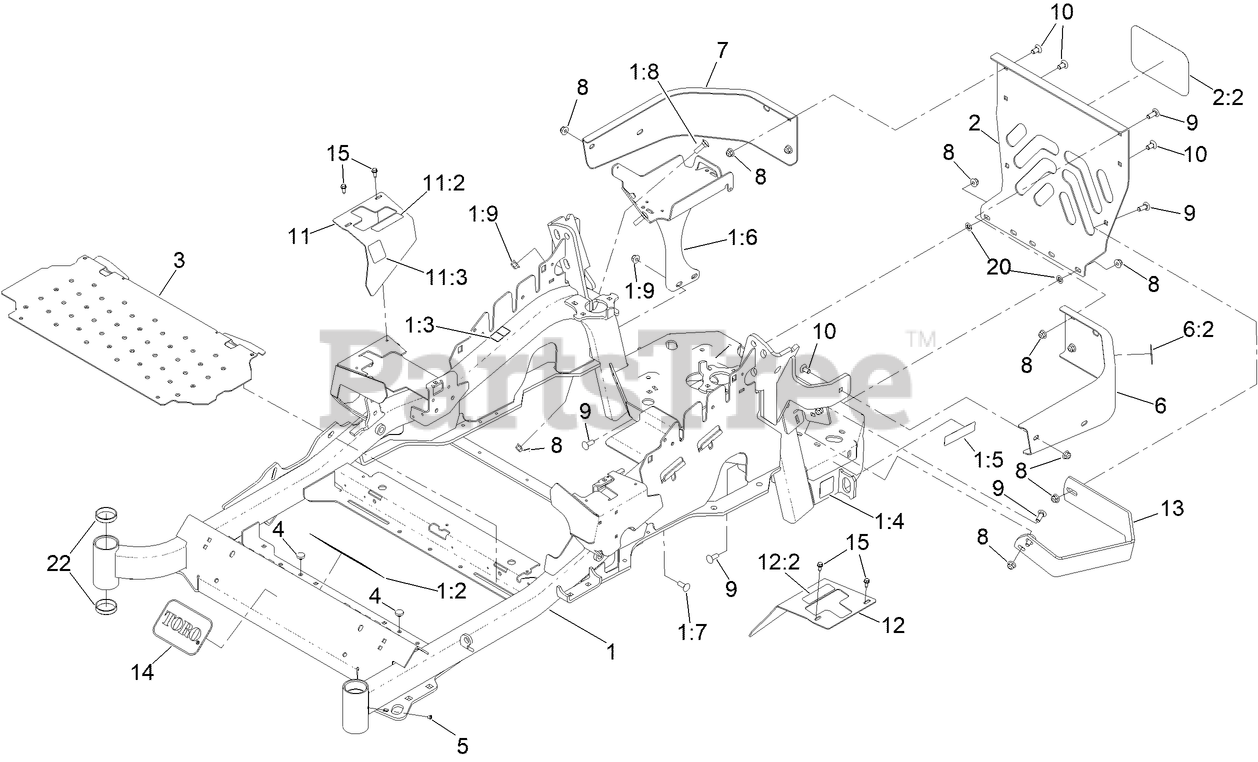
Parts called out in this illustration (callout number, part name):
1	MAINFRAME SERVICE ASM - 48/52
1:2	DECAL-DANGER
1:3	DECAL-WARNING
1:4	DECAL-HAZARD, PINCHED FINGER
1:5	DECAL-ARRESTOR, SPARK
1:6	BATTERY MOUNT ASM
1:7	SCREW-CARR
1:8	BOLT-CARR
1:9	NUT-HF, NI
2	REAR GUARD ASM
2:2	DECAL
3	FLOORPAN
4	BUMPER
6	LH BUMPER ASM
6:2	DECAL-WARNING
7	BUMPER-RH
8	NUT-HF, NI
9	SCREW-CARR
10	SCREW-CARR
11	RH MOTION CONTROL COVER ASM
11:2	DECAL-CONTROL, MOTION
11:3	DECAL-PARK BRAKE, CE
12	LH MOTION CONTROL COVER ASM
12:2	DECAL-CONTROL, MOTION
13	GUARD-MUFFLER
14	DECAL
15	SCREW-HWH
20	NUT-PUSH
22	CUP-BEARING
